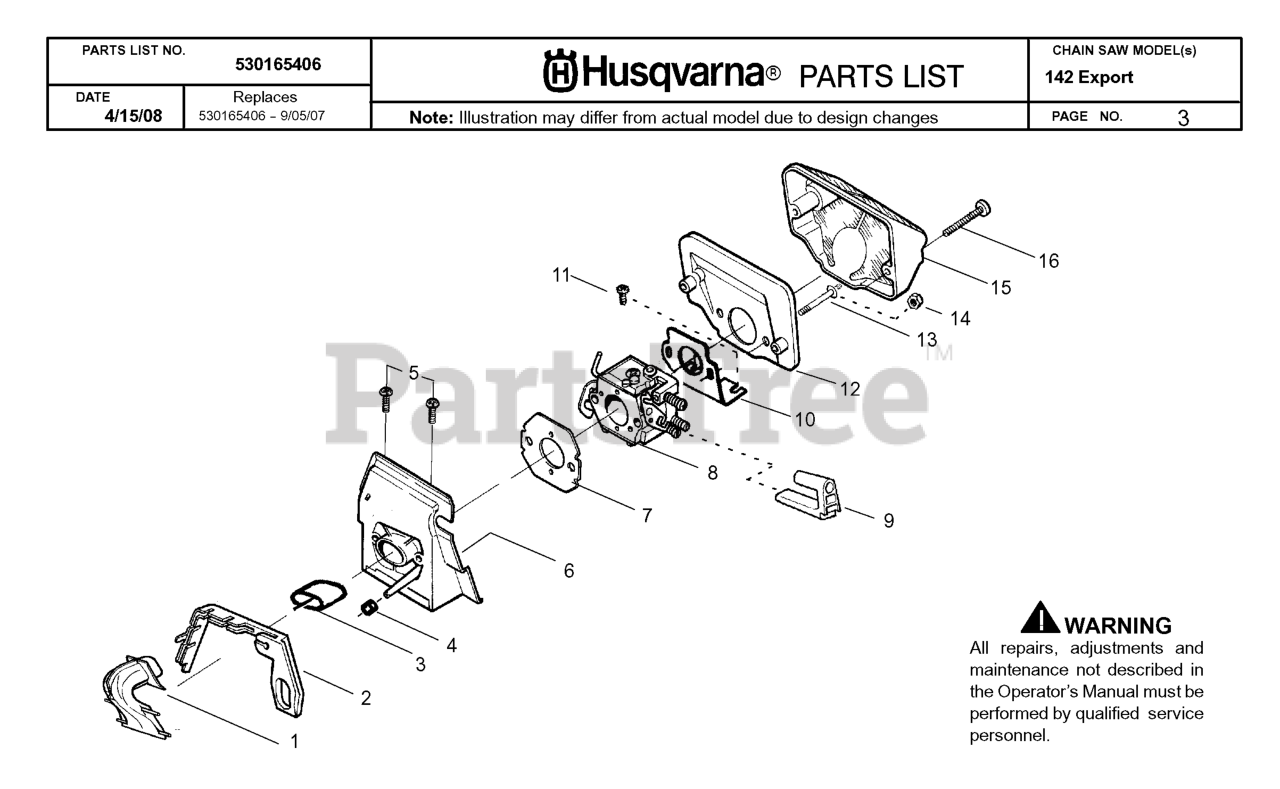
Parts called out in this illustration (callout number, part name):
1	INTAKE HORN
2	TURBO CLEAN SEAL
3	INTAKE PIPE
4	IMPULSE PIPE
6	CARB ADAPTOR
7	GSKT,CARB 36/41
12	AIR FILTER (BOTTOM)
13	STUD-CARBURETOR
15	AIR FILTER - TOP
